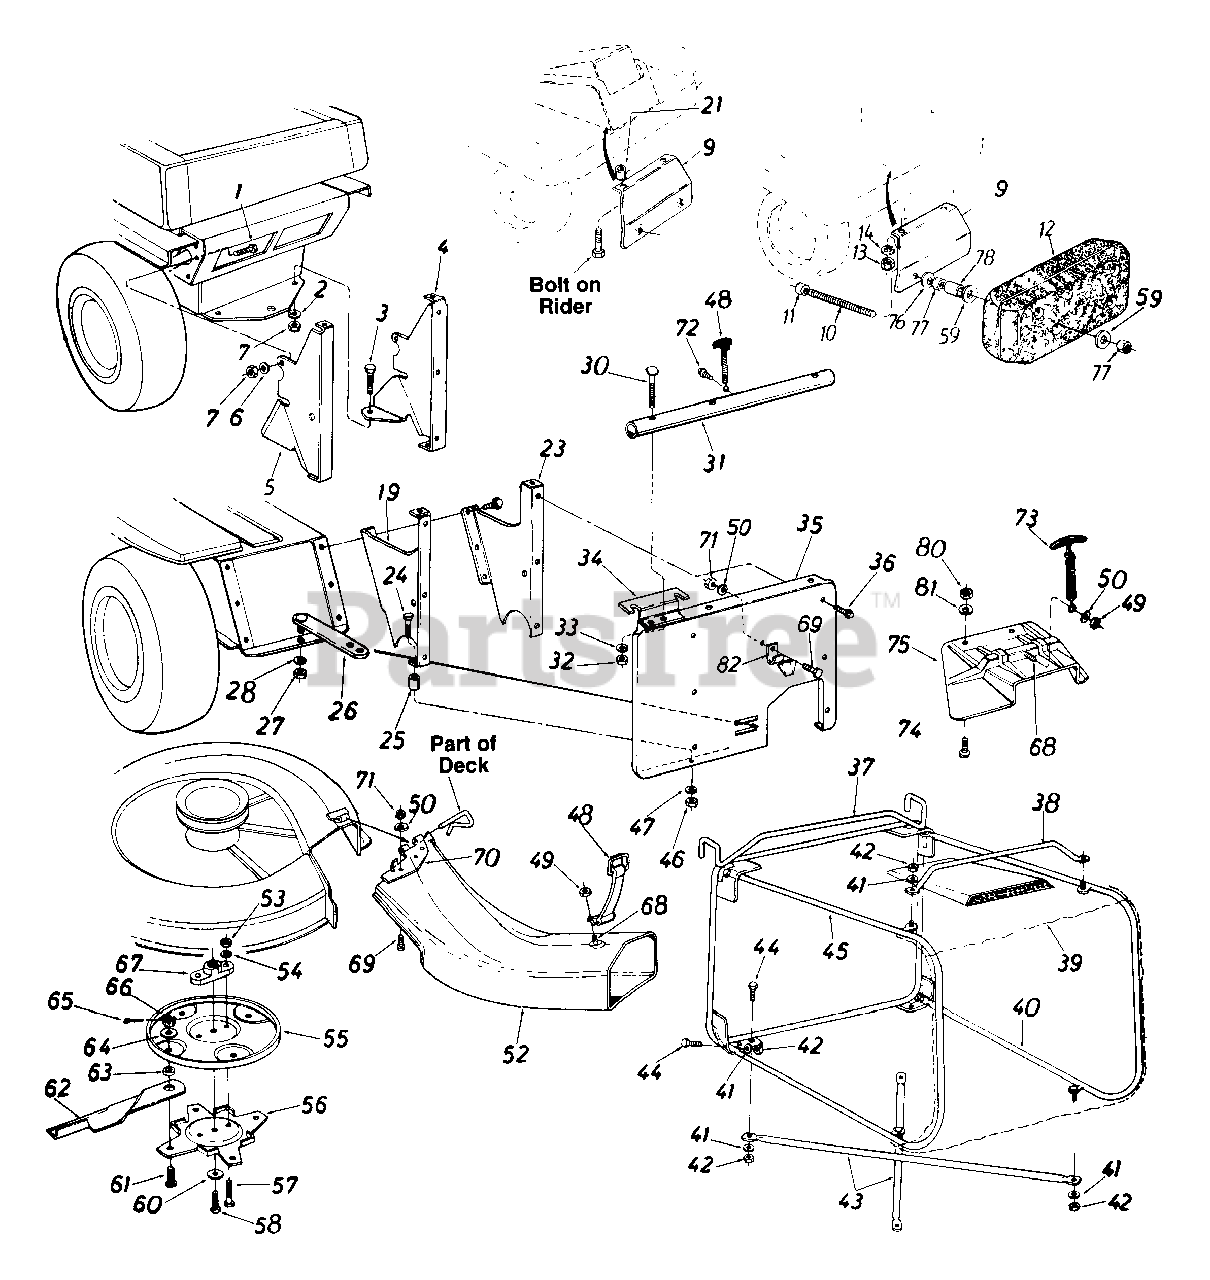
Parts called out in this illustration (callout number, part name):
1	Hex Bolt 5/16-18 x 1" Lg.
2	L-Wash. 5/16" I.D.
4	Catcher Support Brkt.- R.H.
5	Catcher Support Brkt.- L.H.
7	Hex Nut 5/16-18 Thd.
11	Hex Nut 7/16-14 Thd.
12	Counterweight 38 lbs.
19	Catcher Support Brkt.- L.H.
21	Spacer .380" I.D. x 1" O.D. x .32" Lg.
23	Catcher Support Brkt.- R.H.
24	Hex Bolt 5/16-18 x 1.5" Lg.
25	Spacer.38" I.D. x.47" O.D. x 1" Lg.
28	L-Wash. 1/2" I.D.
30	Curved Carriage Bolt 5/16-18 x 1.75" Lg.
36	Hex Wash. Hd. Self-Tap Scr. 1/4-20 x .5" Lg.
40	Catcher Side Frame Ass'y.- R H.
41	Spring-Wash..27" I.D. x .57" O.D. x .025
42	Hex L-Nut 1/2-20 Thd.
43	Bottom Cross Brace
44	Hex Bolt 1/4-20 x .62" Lg.
45	Catcher Side Frame Ass'y.- L.H.
48	Retainer Strap
50	L-Wash. 1/4" I.D.
52	R.D. Banana Chute Ass'y.
53	Hex Nut 5/16-24 Thd.
55	Upper Blade Disc
58	Hex Bolt 3/8-24 x 1.0" Lg.
59	Fl-Wash..45" I.D.
60	Bell-Wash..39" I.D. x 1.38"
61	Shld. Bolt .50" Dia. x .36"
62	30" Blade Tip
63	Spacer .505" I.D. x .75" O.D. x 1.25" Lg.
64	Fl-Wash 5" I.D. x 1.25" O.D.
65	Cotter Pin 3-32" Dia. x 1" Lg.
66	Hex Slotted Nut 1/2-20 Thd.
67	Blade Adapter
68	Hex Bolt 1/4-20 x 5" Lg.
69	Truss Mach Scr 1/4-20 x .5" Lg.
72	Hex AB-Tap Scr. 1/4 x .62" Lg.
73	Hook Latch Ass'y.
74	Truss Mach. Scr. 1/4-20 x .50" Lg.
75	R.D. Chute Extension
76	Bell-Wash. 7/16" I.D. x 1.25" O.D.
77	Hex Nut 7/16-14 Thd.
78	Spacer
81	Fl-Wash. 281" I.D. x .5" O.D.
82	Retainer Hook Brkt.
